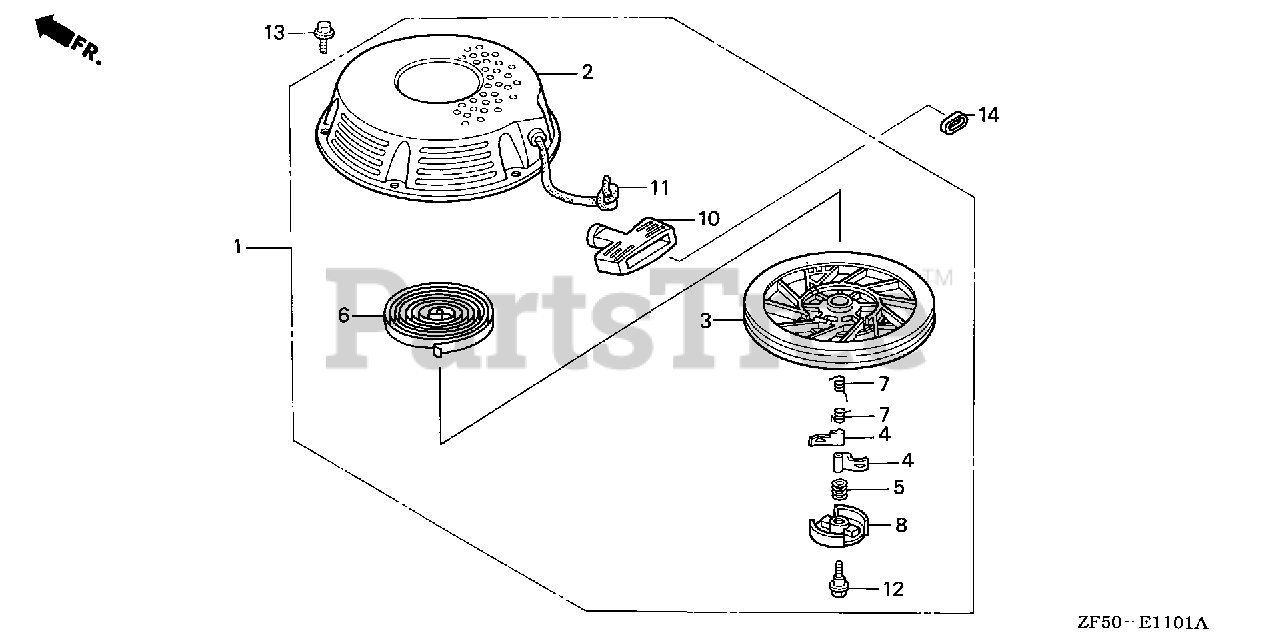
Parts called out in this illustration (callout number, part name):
1	STARTER ASSY., RECOIL *NH1* (BLACK)
1	STARTER ASSY., RECOIL *R8* (BRIGHT RED)
1	STARTER ASSY., RECOIL *T36* (BUNTON YELLOW)
2	CASE, RECOIL STARTER *NH1* (BLACK)
2	CASE, RECOIL STARTER *R8* (BRIGHT RED)
2	CASE, RECOIL STARTER *T36* (BUNTON YELLOW)
3	PULLEY, RECOIL STARTER
4	RATCHET, STARTER
5	SPRING, FRICTION
6	SPRING, STARTER RETURN
7	SPRING, RATCHET
8	RETAINER, SPRING
10	GRIP, STARTER
11	ROPE, RECOIL STARTER
12	SCREW, CENTER
13	BOLT, FLANGE (6X10)
14	GRIP, REINFORCEMENT
